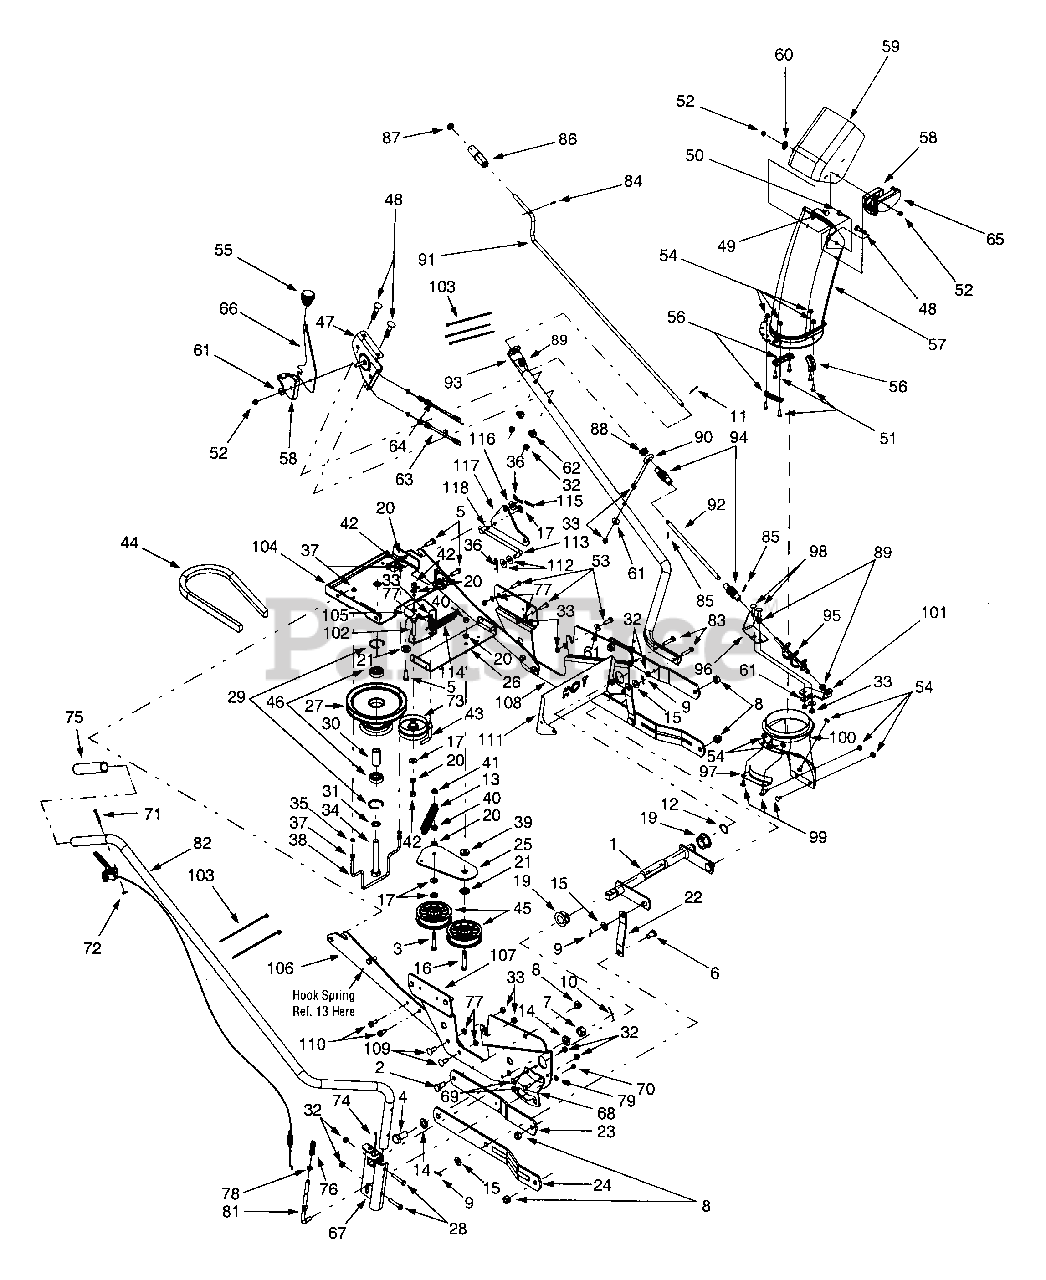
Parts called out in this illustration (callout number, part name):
1	Rod Assembly
2	Hex Cap Screw, 1/2-13 x 1.0
3	Hex Cap Screw, 3/8-24 x 2.0
4	Hex Cap Screw, 5/8-18 x 1.31
5	Hex Cap Screw, 3/8-16 x 1.0
6	Clevis Pin, .5 x .78
7	Slotted Hex Nut, 5/8-18
8	Hex Lock Nut, 1/2-13
9	Cotter Pin, .125 x .75
10	Cotter Pin, 1/8 x 1.25
11	Cotter Pin
12	Snap Ring
13	Extension Spring
14	Flat Washer, .64 x 1.12 x .125
15	Flat Washer, .51 x 1.0 x .060
16	Hex Cap Screw, 3/8-24 x 2.25
17	Flat Washer, .406 x .875 x .059
18	Shoulder Screw, .5 x .29, 3/8-16
19	Flange Bearing wl Flats
20	Lock Washer, 3/8
21	Shoulder Spacer, .625 x .169
22	Link, 4.88
23	Link, 13.25
24	Link, 17.30
25	Idler Pivot Arm
26	Idler Support Bracket
27	Double Pulley, 7.0 x 3.5
28	Hex Cap Screw, 5/16-18 x 1.75
29	Internal Snap Ring
30	Spacer, .635 x 2.0
31	Flat Washer, 5/8 x 1.0 x .063
32	Flange Lock Nut, 5/16-18
33	Hex Nut, 5/16-18
34	Hex Cap Screw, 5/8-18 x 4.25
35	Lock Washer, 1/4
36	Click Pin, .092 x 1.64
37	Hex Nut, 1/4-20
38	Belt Guard Rod
39	Spacer
40	Hex Nut, 3/8-24
41	Nylon Jam Lock Nut, 3/8-24
42	Hex Nut, 3/8-16
43	Belt Keeper Rod
44	Upper V-belt
45	Idler Pulley, 3.5" Diameter
46	Sealed Ball Bearing, .625 x 1.574 x .470
47	Chute Tilt Bracket Assembly
48	Carriage Bolt, 5/16-18 x 1.5
49	Carriage Bolt, 5/16-18 x .75
50	Hex Index Washer Screw, 1/4-14 x .625
51	Hex Cap Screw, 1/4-20 x .75
52	Nylon Hex Lock Nut, 5/16-18
53	Hex Cap Screw, 5/16-18 x 1.0
54	Hex Flange Lock Nut, 1/4-20
56	Chute Flange Keeper
57	Lower Chute
58	Chute Tilt Cable Guide
59	Upper Chute
60	Flat Washer, .344 x 1.125 x .125
61	Bell Washer, .34 x .872
62	Saddle Washer, .32 x .93
63	Chute Cable w/ Clip, 54.5"
64	Chute Cable, 54.5"
66	Chute Tilt Handle
70	Hex Index Washer Screw #10-16 x .375
71	Pan Phillips Screw, #10-24 x .75
72	Flat Weld Nut, #10-24
73	Flat Idler Pulley, 3.25
74	Heavy Duty Spirol Pin, 1/4 x 1.5
75	Handle Grip
76	Compression Spring, .406 x .531 x 1.75
77	Lock Washer, 5/16
78	Flat Washer, .385 x .62 x .063
79	Flat Washer, .194 x .62 x .063
81	Lift Index Rod
84	Rolled Pin, 1/8 x .63
85	Spirol Pin, .125 x .82
86	Crank Knob
87	Push Cap, 3/8 ID
88	Rubber Grommet, .44 x .94 x.5
89	Plastic Bushing
90	Eye Bolt
91	Chute Crank Rod, .38 x 28
92	Rod, .375 x 11.375
94	Joint Block Assembly
95	Chute Crank Assembly
98	Splined Carriage Screw, 5/16-18 x 1.0
99	Carriage Screw, 1/4-20 x .5
100	Adapter Chute
101	Chute Crank Bracket
102	Hex Cap Screw, 3/8-16 x 2.0
103	Cable Tie
107	RH Side Plate
108	LH Side Plate
109	Carriage Bolt, 3/8-16 x 1.0
110	Self-tapping Screw, 5/16-18 x .875
111	Heat Shield
112	Flat Washer, .406 x 1.0 x .030
113	Clutch Adjustment Control Rod
114	Extension Spring, .75 x 5.06
115	Internal Cotter Pin
116	Flat Washer, .531 x 1.062 x .134
117	Idler Engagement Bracket
118	Ferrule, 3/8-24 x .375
